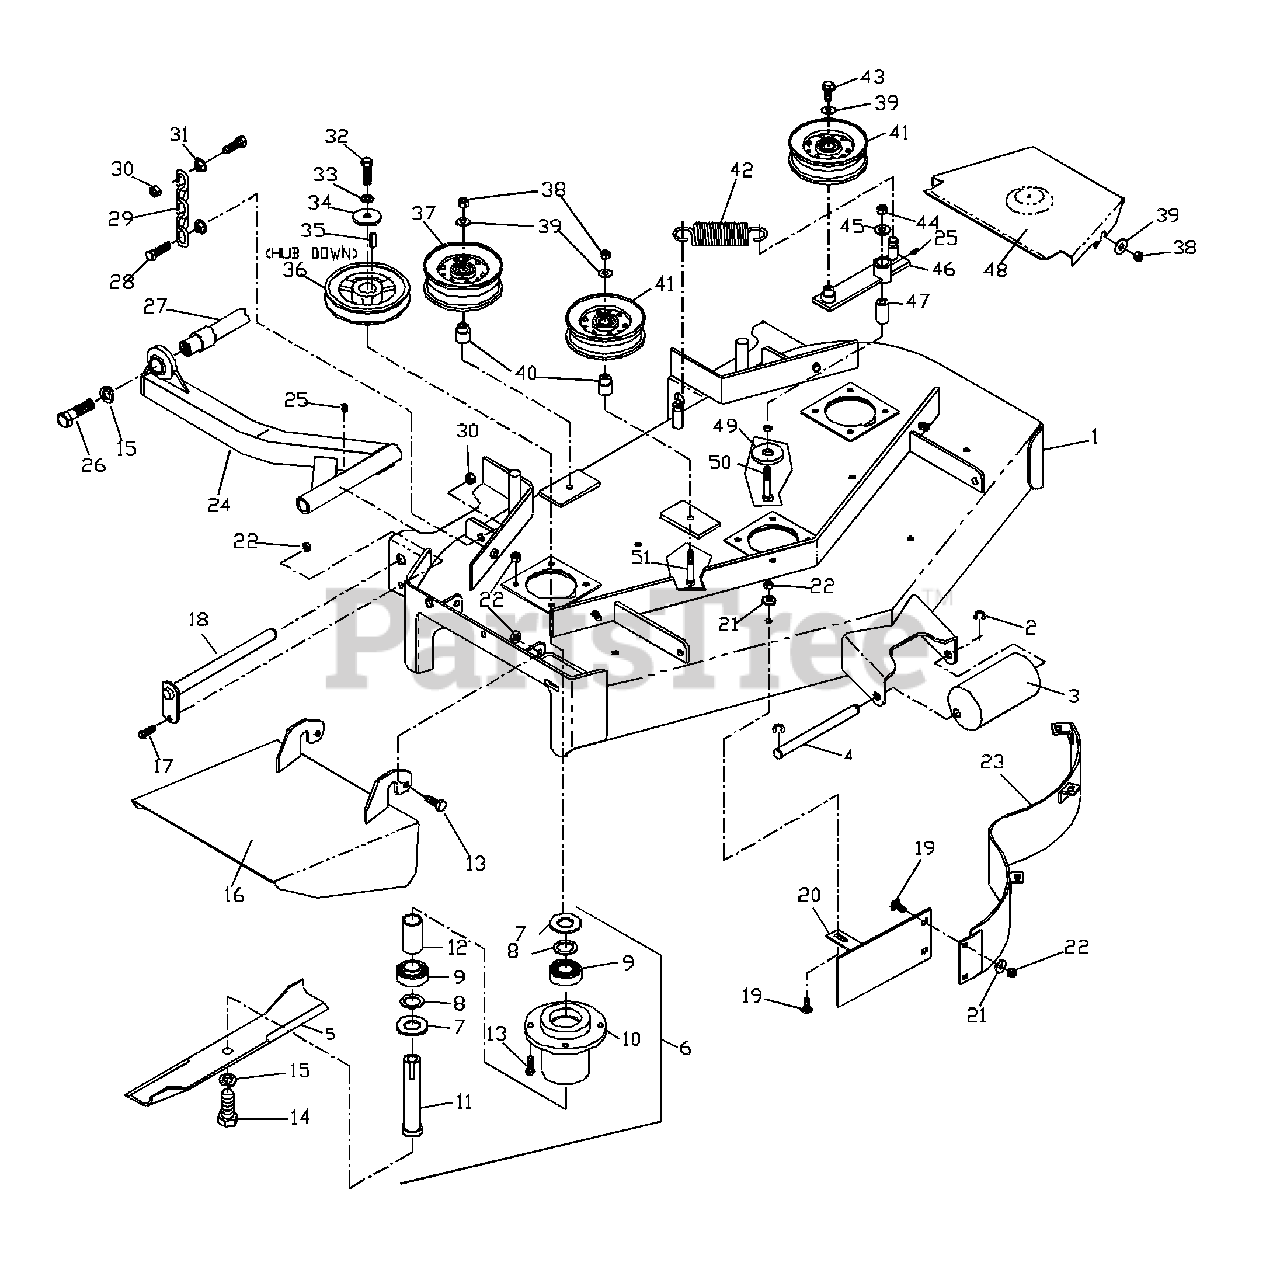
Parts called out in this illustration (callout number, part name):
1	DECK W/DECALS
2	1/2" E-RING
3	ROLLER, LONG
4	AXLE, ROLLER
5	BLADE 14 7/8"
6	CUTTER HOUSING, COMPLETE
7	MACHINERY BUSHING 10GA.
8	MACHINERY BUSHING 18GA.
9	BEARING
13	HCS 5/16C X 1
14	HCS 5/8F X 1 1/4
15	LOCKWASHER
16	DISCHARGE CHUTE
17	HCS 5/16C X 3/4
19	CARRIAGE BOLT 5/16 X 5/8
20	CENTER BAFFLE
21	WASHER 5/16 STD.
22	NUT 5/16 CTR. LOCK
23	MAIN BAFFLE
24	STRUT - RIGHT
24	STRUT - LEFT
25	1/4-28 ZERK
26	HCS 5/16C X 2
27	STRUT MT. WLD.
28	HCS 7/16C X 1 1/2
30	7/16C CTR. LOCK
31	7/16C WHIZ NUT
32	HCS 7/16F X 1 1/2
33	7/16 LOCKWASHER
35	KEY 1/4 SQ. X 1 1/8
37	IDLER PULLEY 1.62
38	NUT 3/8C CTR. LOCK
39	WASHER 3/8 STD.
40	IDLER BUSHING
41	IDLER PULLEY 1.31
43	HCS 3/8C X 1
44	NUT 1/2C NYLOC
45	WASHER 1/2 STD.
47	PIVOT BUSHING
48	BELT SHIELD
49	SUPPORT WASHER
50	HCS 1/2C X 3 1/4
51	HCS 3/8C X 2 1/2
53	DECAL, NO STEP
54	DECAL, CPSC
55	DECAL, DANGER
